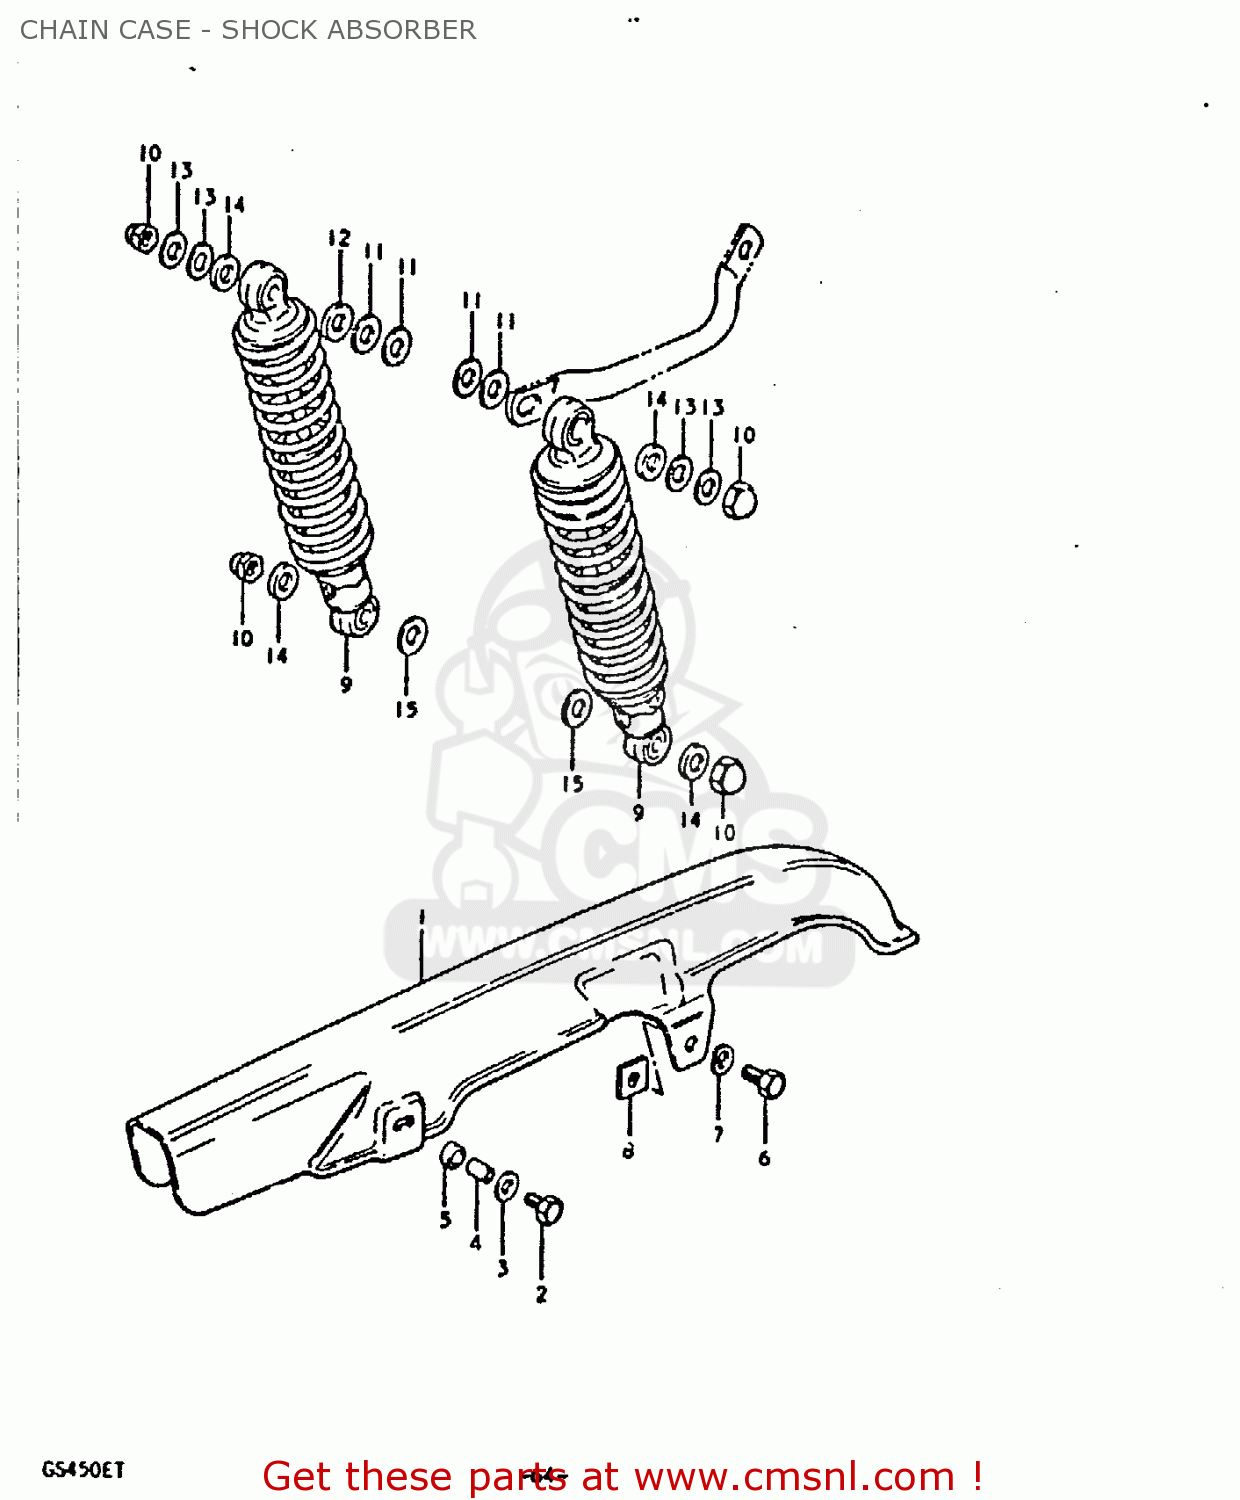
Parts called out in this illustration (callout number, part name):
1	CASE,CHAIN
2	BOLT
3	WASHER(6.5X18X1)
4	SPACER (6.1X8X5.2)
5	CUSHION
6	BOLT, UPPER
7	LOCK WASHER
8	NUT,CHAIN CASE RR
9	SHOCK ABSORBER, REAR
10	NUT, LOWER LH
11	WASHER
12	WASHER (12.5X24X3.2)
13	WASHER
14	WASHER(10.5X24X3.2)
15	WASHER (12.5X24X1.6)
